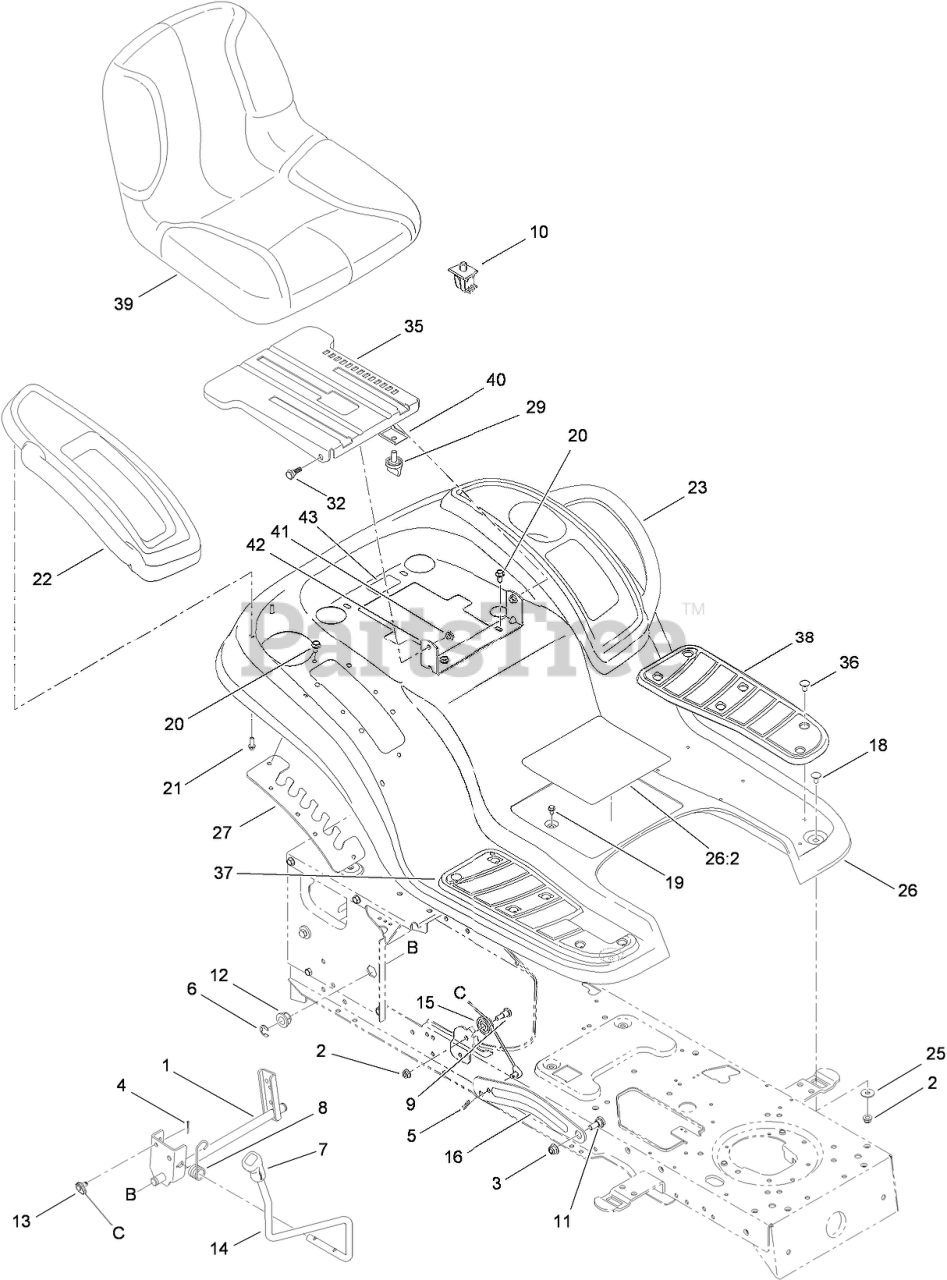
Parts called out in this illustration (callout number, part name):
1	LIFT SHAFT ASM
2	NUT-LOCK, FLANGE
3	NUT-LOCK, FLANGE
4	PIN-COTTER
5	PIN-COTTER
6	RING-E
7	GRIP-HANDLE
8	SPRING-TORSION
9	SPACER
10	Switch-Seat
11	BOLT-SHOULDER
12	BEARING-FLANGE
13	CABLE-LIFT
14	HANDLE-LIFT
15	PULLEY-ROLLER
16	ARM-LIFT
19	SCREW-HWHTF
20	SCREW-TAP
21	SCREW-TAP
22	COVER-FENDER, RH
23	COVER-FENDER, LH (W/CUPHOLDER)
25	WASHER-FLAT
26	FENDER WITH DECAL
26:2	DECAL-SAFETY
27	BRACKET-ADJUSTING, LIFT
32	BOLT-SHOULDER
35	BRACKET-MOUNT, SEAT
36	CLIP-RATCHET, FASTENER
37	PAD-FOOT, RH
38	PAD-FOOT, LH
39	SEAT-HIGH
40	BRACKET-KNOB, ADJUSTMENT
41	NUT-LOCK, FLANGE
42	BRACKET-PIVOT, SEAT
43	DECAL-TORO HOTLINE
